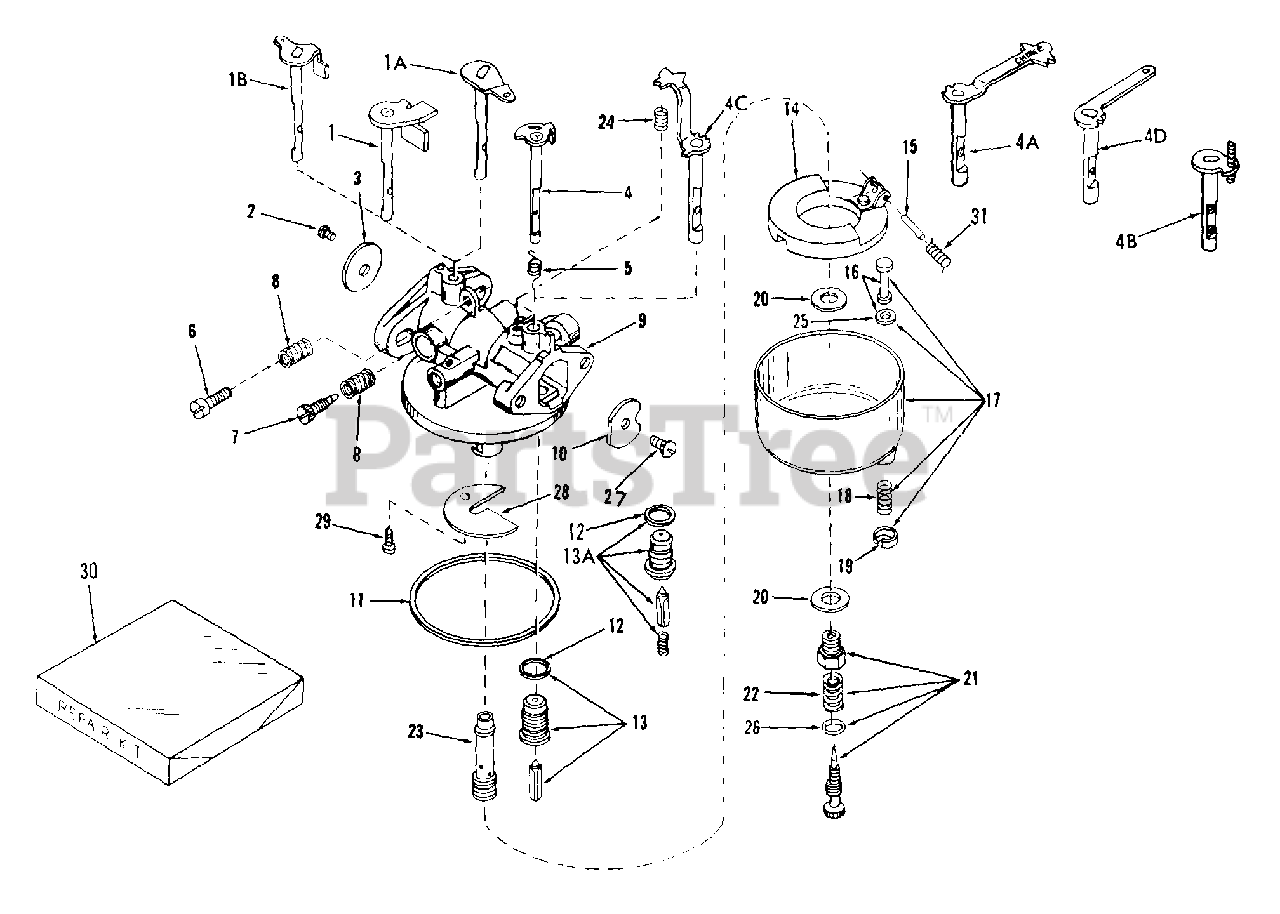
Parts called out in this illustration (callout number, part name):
1B	"Shaft & Lever, Throttle
2	Screw, Sems, 6-32 x 3/16
3	Shutter, Throttle
4A	Shaft & Lever Assy., Choke
6	Screw, Throttle adjusting
7	Needle, Idle
8	Spring, Adj. needle
9	Body Assy., Carburetor
10	Shutter, Choke
11	Gasket, Bowl-to-body
12	Gasket', Seat
13	Valve, Seat, Gasket Assy.
15	Shaft, Float
16	Stem Assy., Bowl drain
17	Bowl Assy.,
18	Spring, Bowl drain
19	Retainer, Bowl drain stem
20	Gasket, Bowl-to-body
21	Needle Assy., Power Adj. (Incl. 22,26 )
22	Spring, Power needle
23	Nozzle, Main
24	Spring, Choke stop
25	Gasket, Drain stem
26	"O" Ring
27	Screw, Sems
28	Baffle, Carburetor
29	Screw, Baffle
30	Repair Kit
31	Spring, Float shaft
